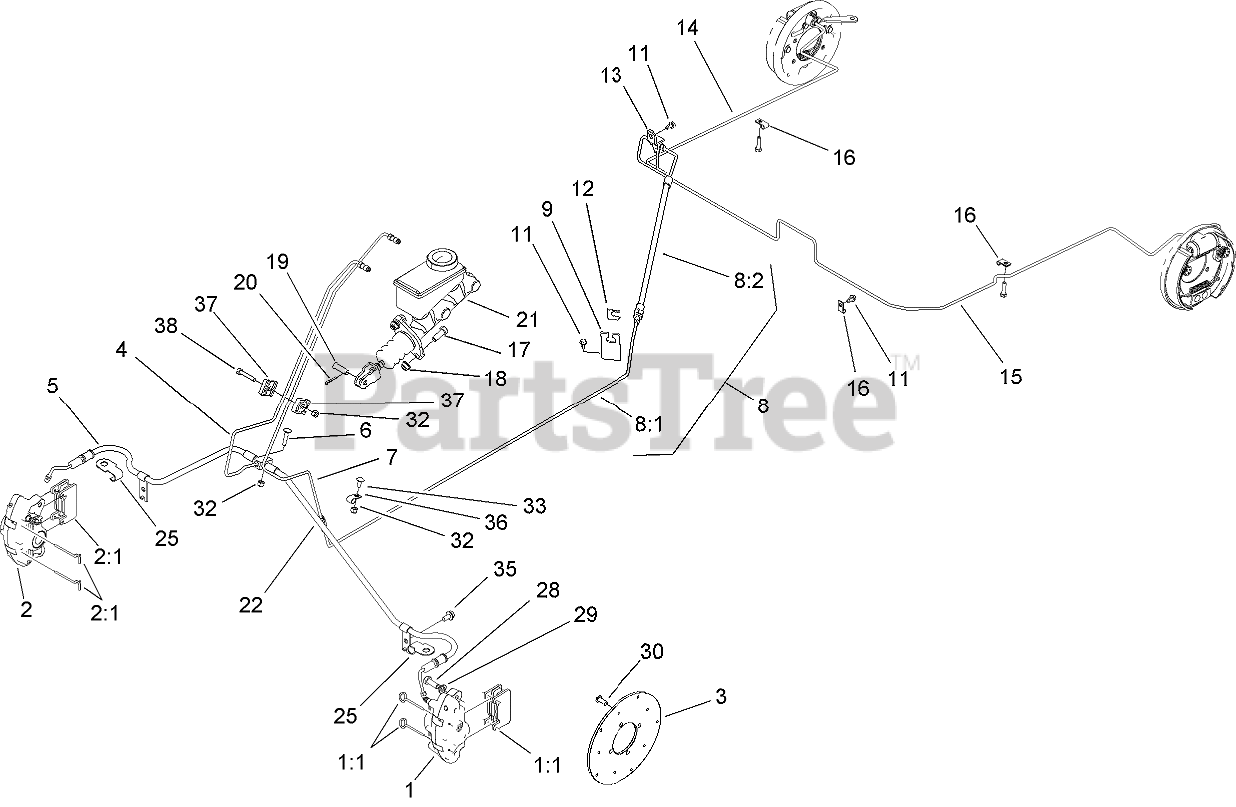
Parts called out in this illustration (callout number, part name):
1	CALIPER-LH
1:1	FRICTION PAD AND PIN KIT
2	CALIPER-RH
2:1	FRICTION PAD AND PIN KIT
4	TUBE-BRAKE, FRONT
5	FRONT HOSE ASM
6	SCREW-CARR
7	TUBE-BRAKE, REAR
8	REAR BRAKE HOSE ASM
8:1	TUBE-BRAKE, REAR
8:2	HOSE-BRAKE, REAR
9	BRACKET-HOSE, BRAKE
11	SCREW
14	TUBE-BRAKE, REAR (RH)
15	TUBE-BRAKE, REAR (LH)
16	CLIP-CLOSED, INSULATED
17	SCREW-HH
18	NUT-HHF, WHIZ
19	PIN-CLEVIS
20	PIN-COTTER
21	MASTER CYLINDER ASM
22	UNION
25	BRACKET-HOSE
28	SCREW-HH
29	WASHER-LOCK
30	SCREW-HSBH
32	NUT-LOCK, NI
33	SCREW-CARR
35	SCREW-HWHTF
36	CLAMP-R
37	CLAMP-TUBE
38	SCREW-HH
